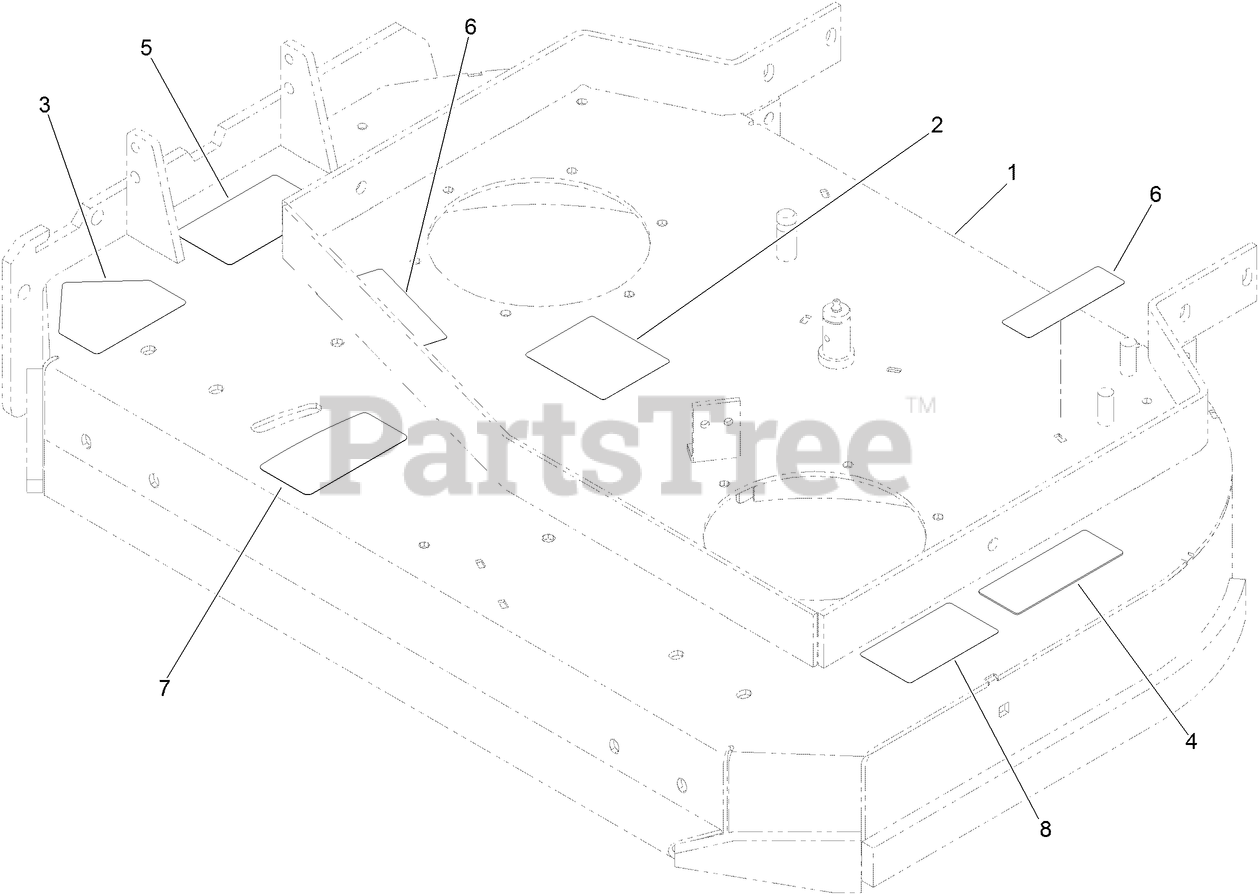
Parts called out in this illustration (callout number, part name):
1	36 INCH DECK ASM
2	DECAL-ROUTING, BELT
3	DECAL-DANGER
4	DECAL-TORQUE, BOLT
5	DECAL-DANGER
6	DECAL-MISSING, COVER
7	DECAL-ADJUSTMENT, BAFFLE
8	DECAL-DANGER
